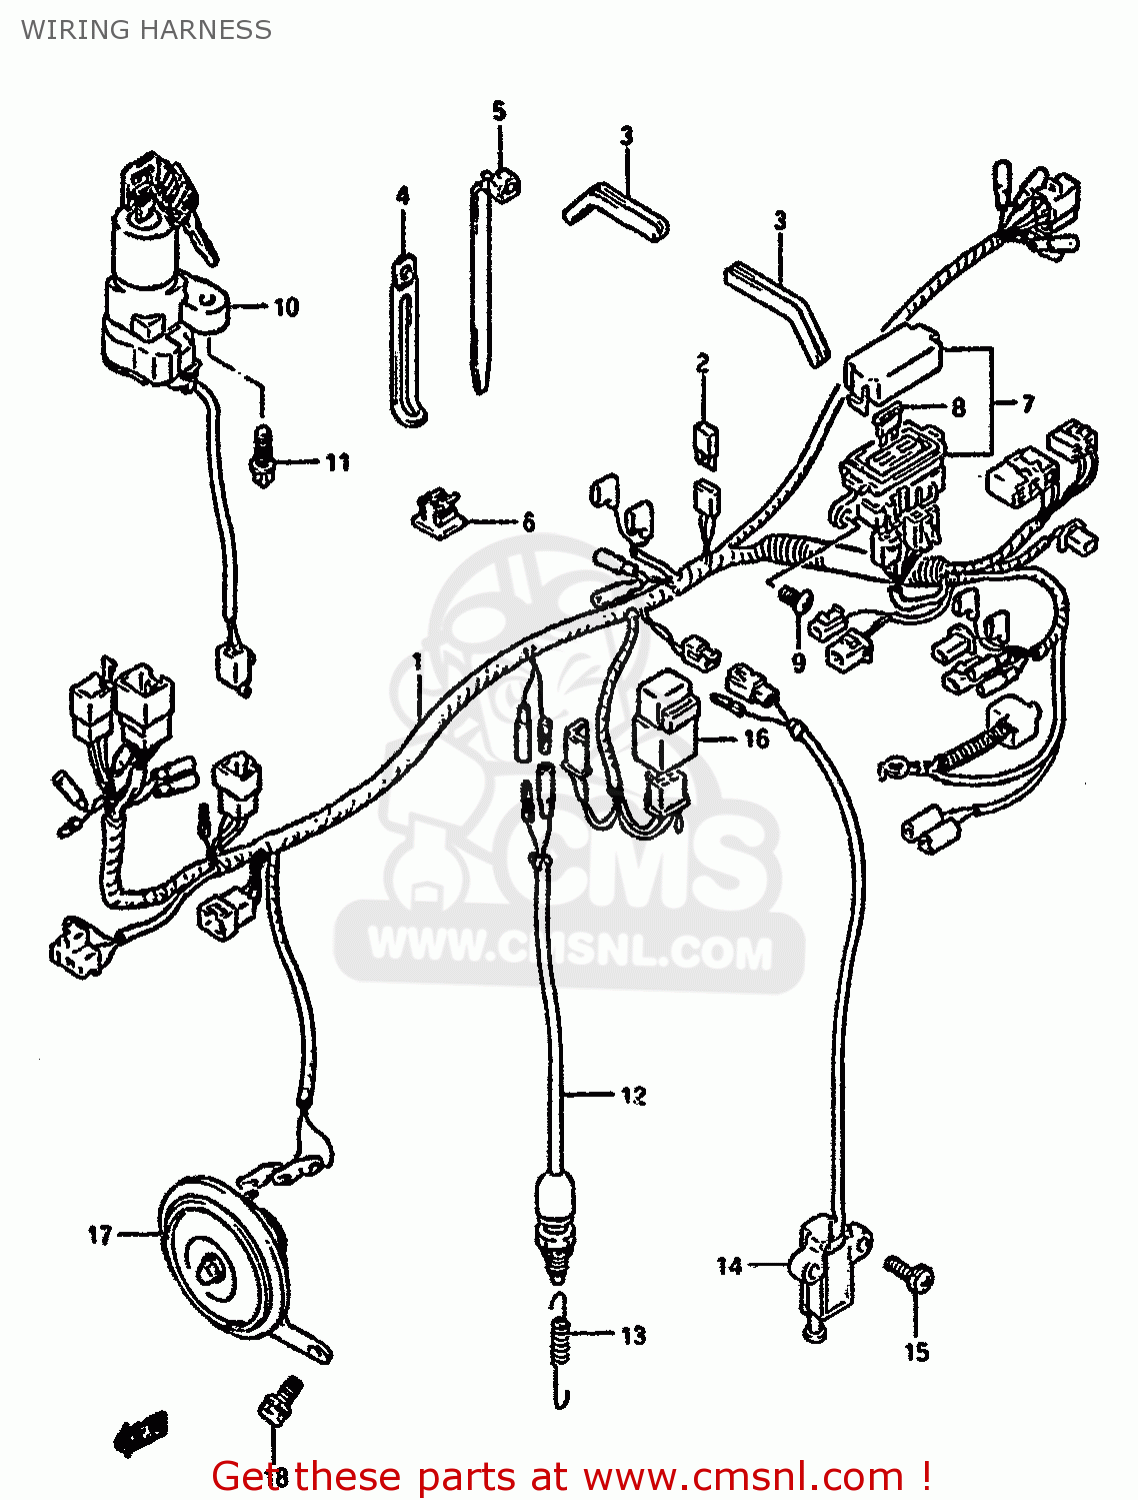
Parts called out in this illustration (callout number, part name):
1	HARNESS,WIRING
2	DIODE(STANLEY DE8804)
3	PROTECTOR,WIRING HARNESS
4	CLAMP
5	CLAMP
6	CLAMP
7	BOX ASSEMBLY,FUSE
8	FUSE(10A)
9	SCREW 6X12
10	LOCK ASSEMBLY,STEERING
11	SCREW(6X18)
12	SWITCH ASSY,STOP LAMP
13	SPRING
14	SWITCH ASSY,SI
15	SCREW
16	RELAY ASSY
17	HORN ASSEMBLY
18	BOLT
